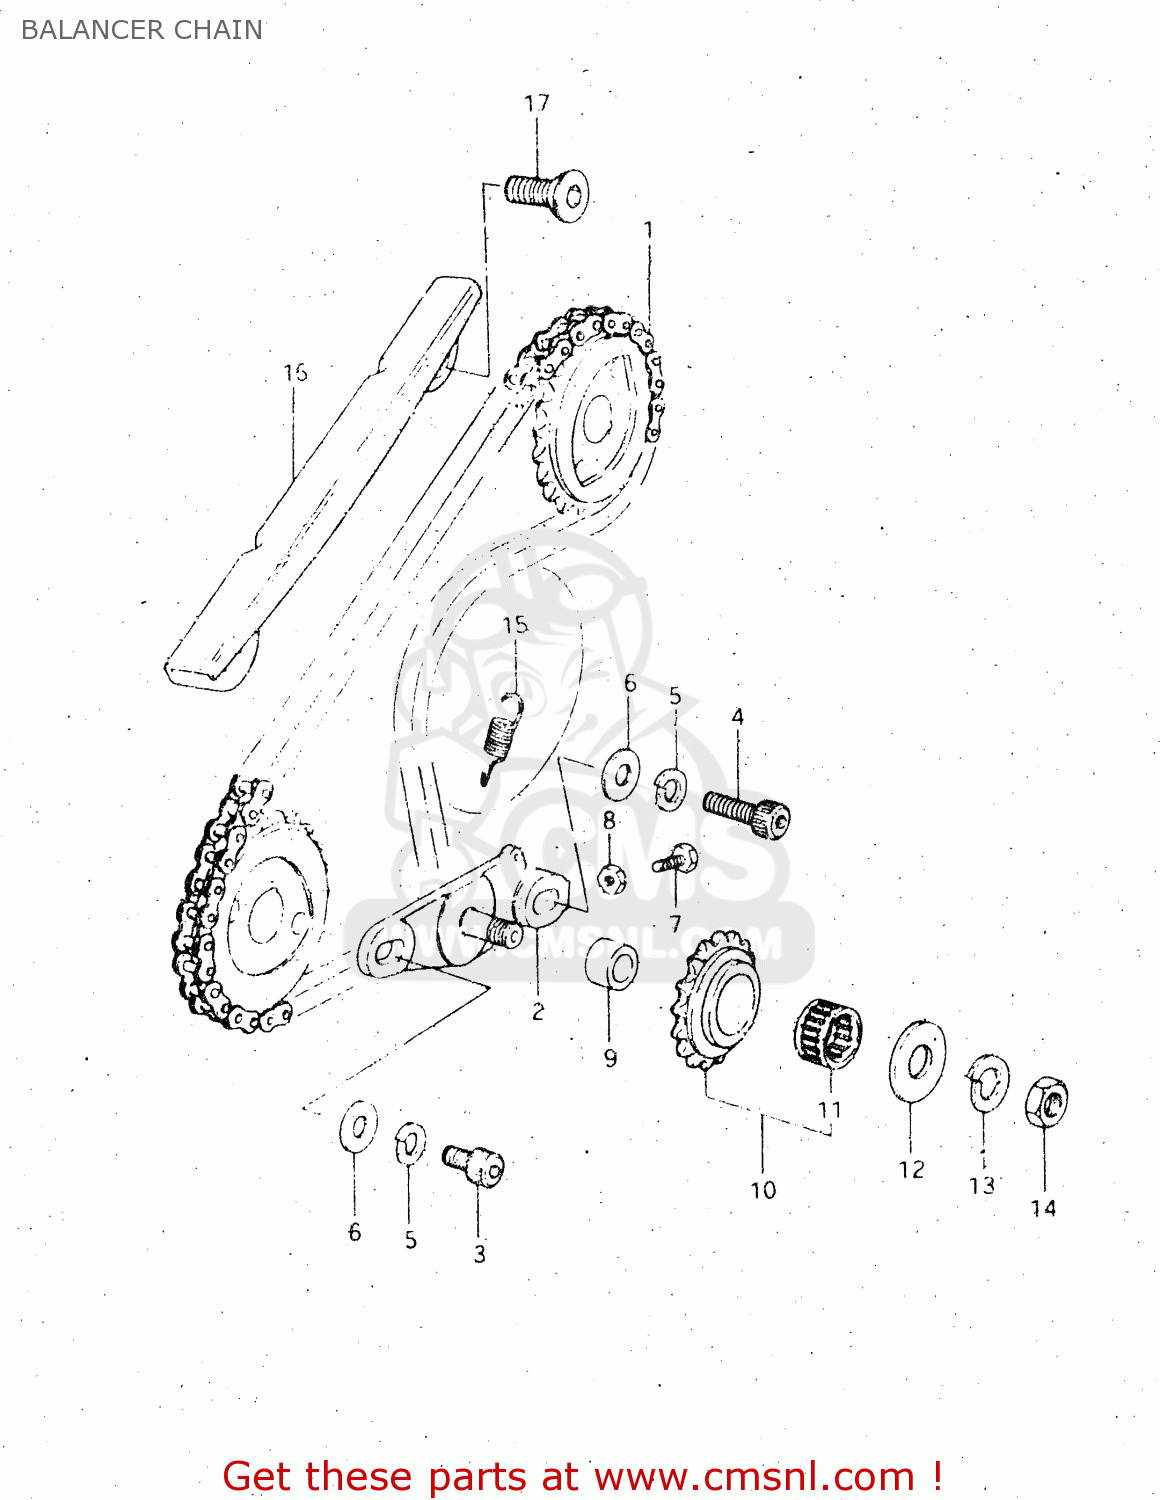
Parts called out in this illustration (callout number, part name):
1	GOVERNOR ASSEMBLY,EXHAUST
2	BRACKET,BALANCER CHAIN TENSIONER
3	BOLT(8X22)
4	BOLT, REAR (8X30)
5	LOCK WASHER
6	WASHER
7	BOLT 5X20
8	NUT
9	SPACER,TENSIONER SPROCKET
10	ROD,EXHAUST VALVE
11	BEARING(17X23X12)
12	WASHER
13	WASHER,LOCK 12
14	NUT
15	SPRING
16	GUIDE,BALANCER CHAIN
17	SCREW
